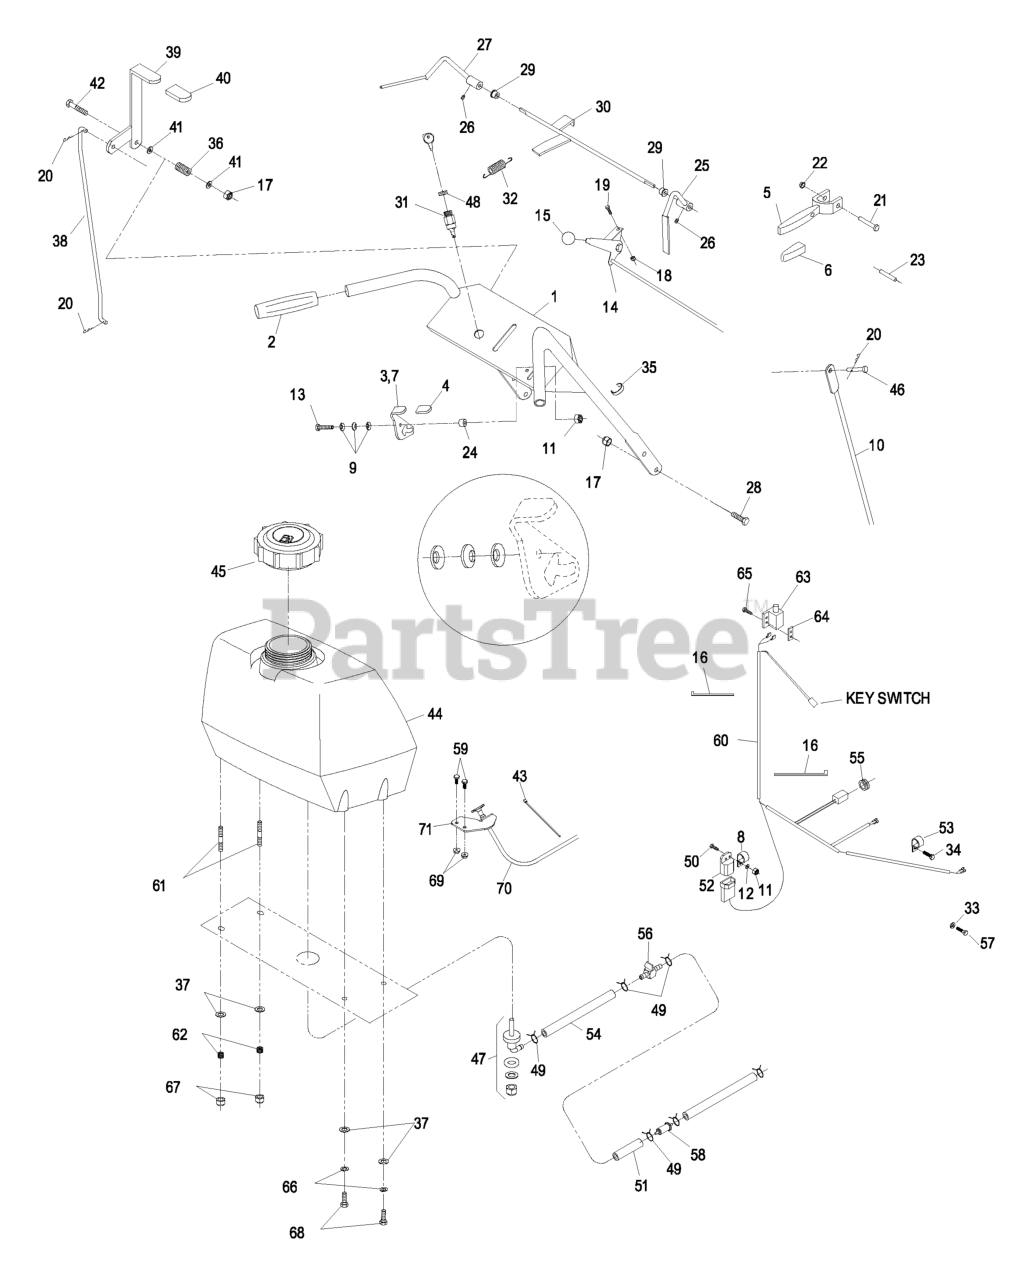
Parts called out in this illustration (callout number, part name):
1	KIT,HANDLE/DECALS METRO
4	GRIP-LATCH
5	DRIVE LEVER ASM
6	GRIP-LEVER, DRIVE
8	CLIP-LOOM
9	WASHER-SPRING
10	LINKAGE-WHEEL, DRIVE
11	NUT-LOCK, NI
12	WASHER-FLAT
13	SCREW-HH
14	THROTTLE CABLE ASM
15	KNOB-BALL
16	TIE-CABLE
17	NUT-LOCK, NI
18	NUT-LOCK, NI
19	BOLT-CARR
20	PIN-COTTER
21	PIN-LEVER, DRIVE
22	NUT-PUSH
23	PIN-ROLL
25	LEVER-RH
26	SCREW-SET
27	LEVER-LH
28	SCREW-HH
29	BUSHING-NYLON
30	WLD,ROD OPC
31	SWITCH & KEY (INCLUDES NU
32	SPRING-EXTENSION
33	WASHER-LOCK
34	SCREW-HH
35	CLIP-CABLE
36	SPRING-COMPRESSION
37	WASHER-PLAIN
38	LINKAGE-BLADE, UPPER
40	GRIP-LEVER
41	WASHER-FLAT
42	SCREW-HH
43	TIE-PLASTIC
44	ASM,FUEL TANK W/B
45	CAP-FUEL, GAS
46	PIN-CLEVIS
47	FITTING-FUEL, BULKHEAD
48	NUT-SWITCH, IGNITION
50	SCREW-HH
51	HOSE-FUEL
52	MODULE-INTERLOCK
53	CLIP-LOOM
54	HOSE-FUEL
55	GROMMET
56	VALVE-FUEL
57	SCREW-HH
58	Kawasaki Pn 41019-1055 W/6" Fuel Line
59	SCREW-HH
60	HARNESS-WIRING
61	STUD
62	SPRING-TANK, FUEL
63	SWITCH-OPEN, NORMALLY
64	PLATE-TAPPED
65	SCREW-PPH
66	WASHER-LOCK
67	NUT-LOCK, NI
68	SCREW-HH
70	CABLE-CHOKE
71	BRACKET-CABLE, CHOKE
